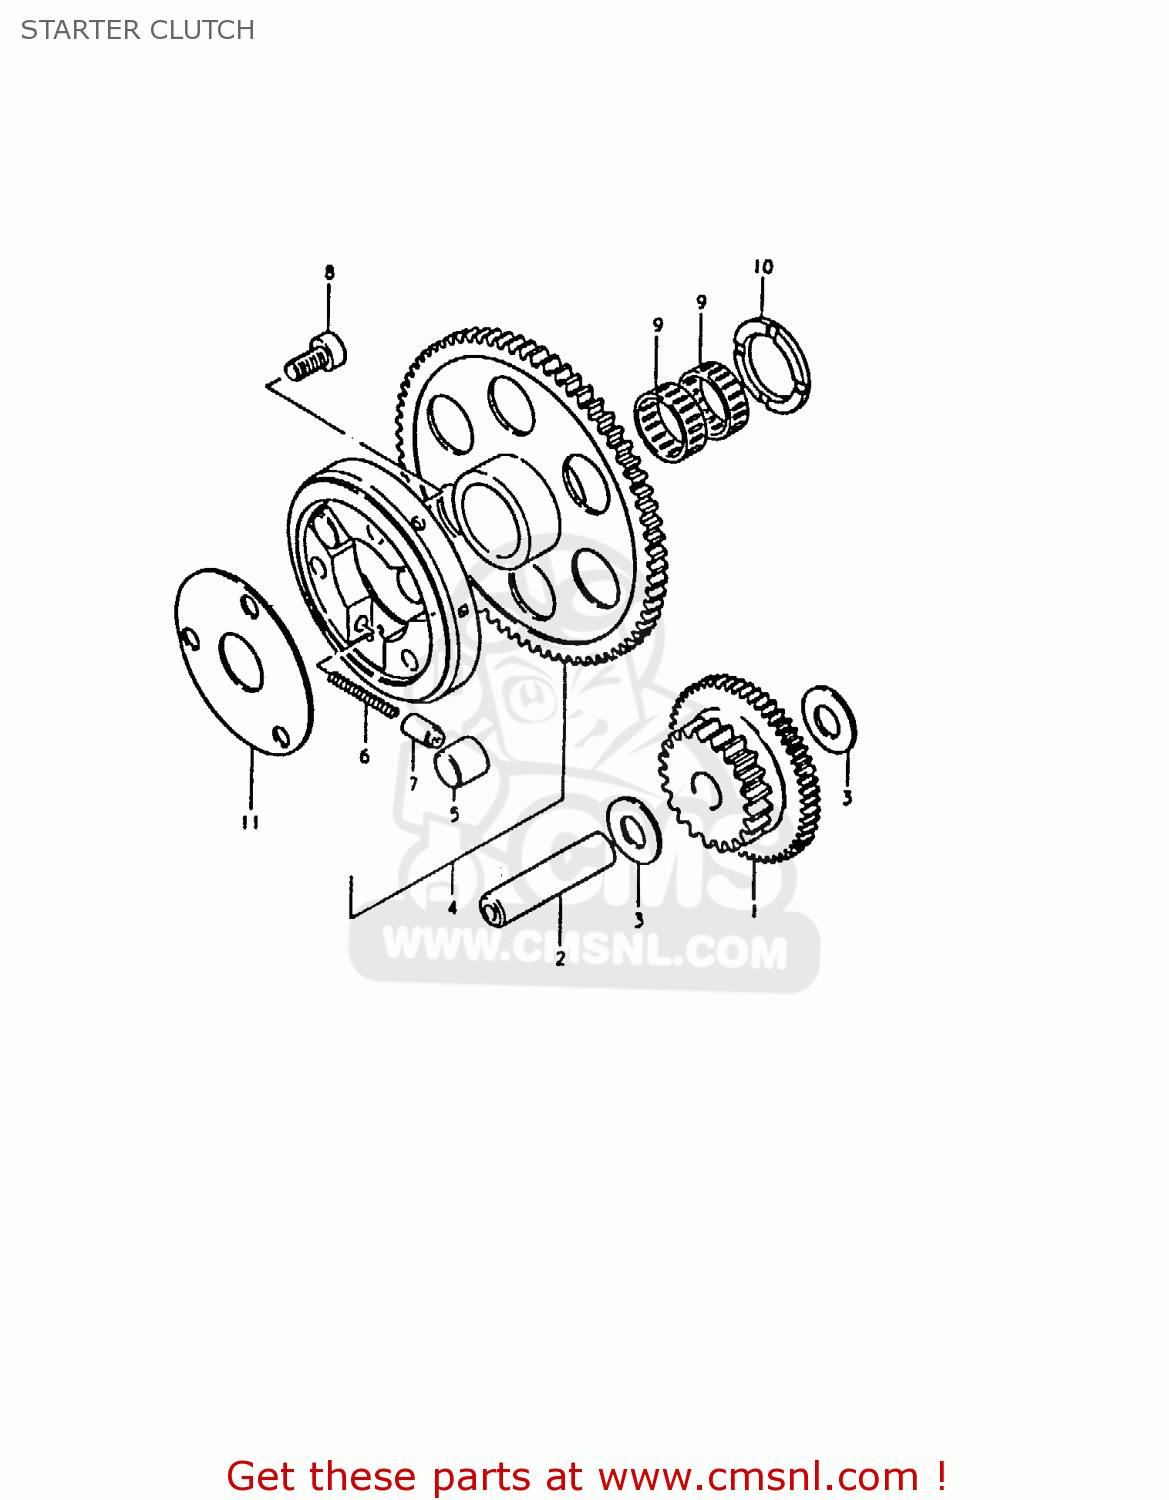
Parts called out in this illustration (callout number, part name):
1	GEAR,STARTER IDLE
2	PIN(7.4X13X56)
3	WASHER(13.3X25X0.85)
4	CLUTCH SET,STARTER
5	ROLLER(15X13)
6	SPRING
7	PIECE,PUSH
8	BOLT
9	BEARING(25X29X9.9)
10	WASHER(25X38X2.5)
11	SHIM,STARTER CLUTCH HUB
